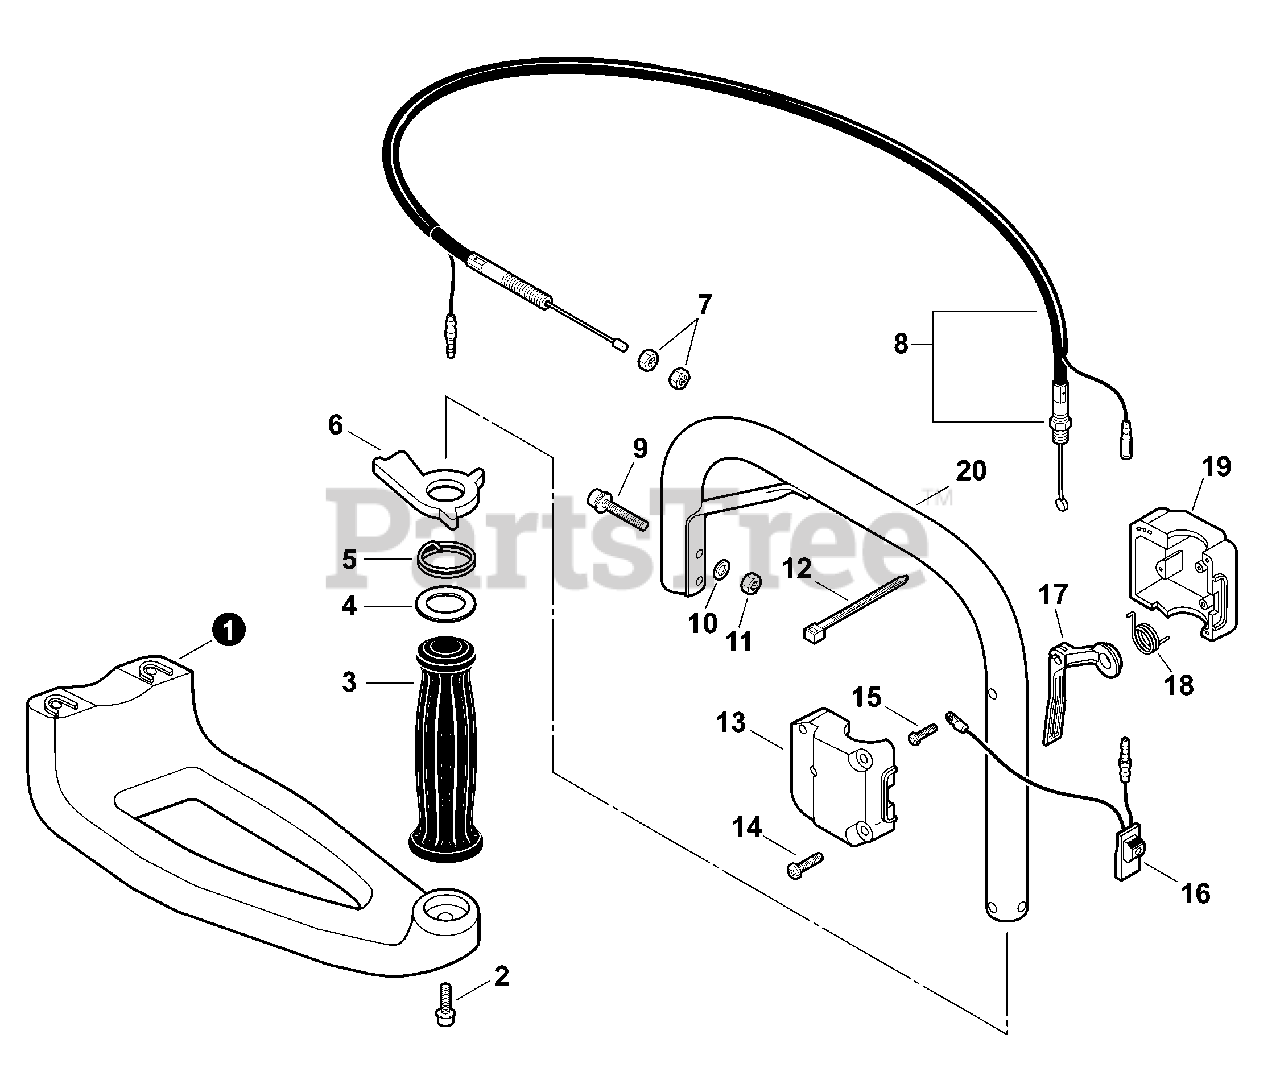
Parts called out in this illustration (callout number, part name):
2	BOLT 5×16
3	GRIP, HANDLE
5	SPRING, THROTTLE LOCKOUT
6	LOCKOUT, THROTTLE
8	CABLE ASSY, CONTROL
9	BOLT M5×35
10	WASHER 5.3×10×1
11	NUT, LOCK M5
12	TIE, CABLE
13	BRACKET, LEFT CONTROL
14	SCREW 4×25
15	SCREW 4×30
16	SWITCH, ON-OFF
17	TRIGGER, THROTTLE
18	SPRING, THROTTLE RETURN
19	BRACKET, RIGHT CONTROL
20	HANDLE, REAR
